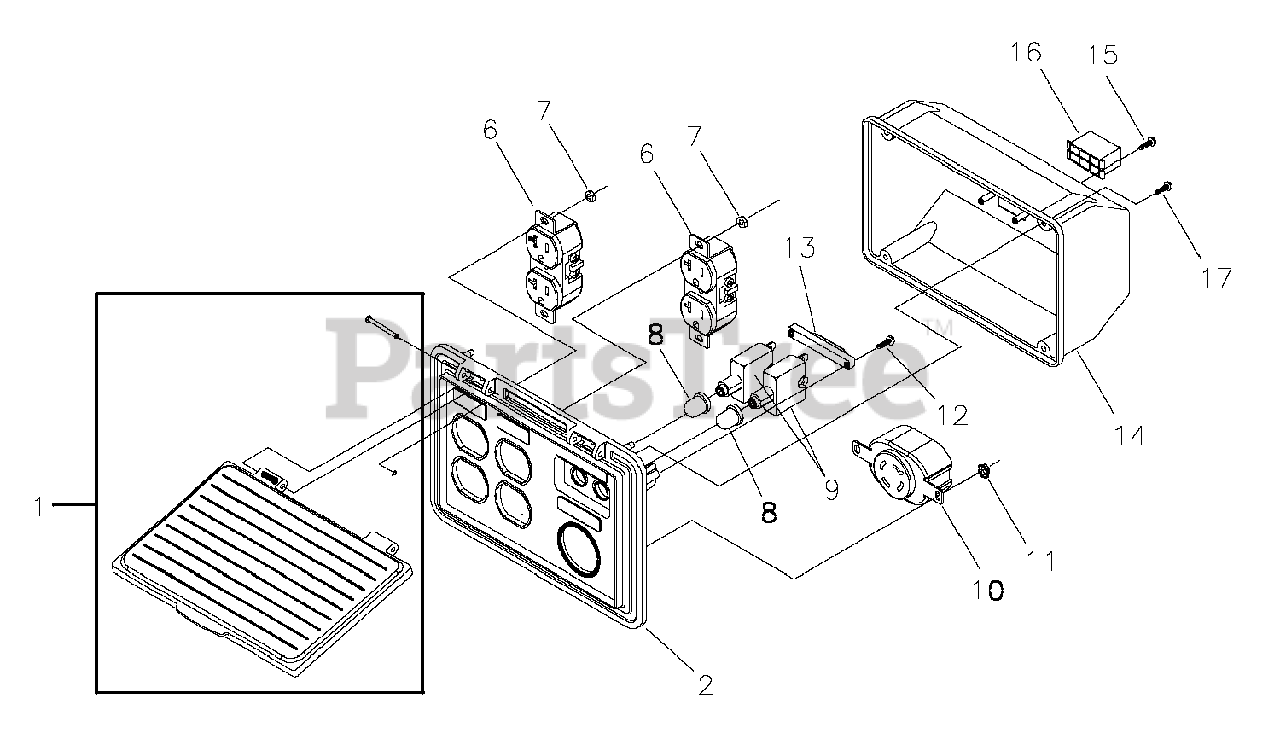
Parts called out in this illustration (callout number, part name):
1	KIT, Cover Control Panel
2	CONTROL PANEL, Compact
6	OUTLET, 120V, 20Amp, Duplex
8	CAP, Circuit Breaker
9	BREAKER, Circuit
10	OUTLET, 120/240V Locking, 20A
13	BAR, Retaining
14	COVER, Back, Control Panel
15	* SCREW, 3 x 18, Tapping
16	HOUSING, Receptacle
17	* SCREW, 3.5 x 14, Tapping
